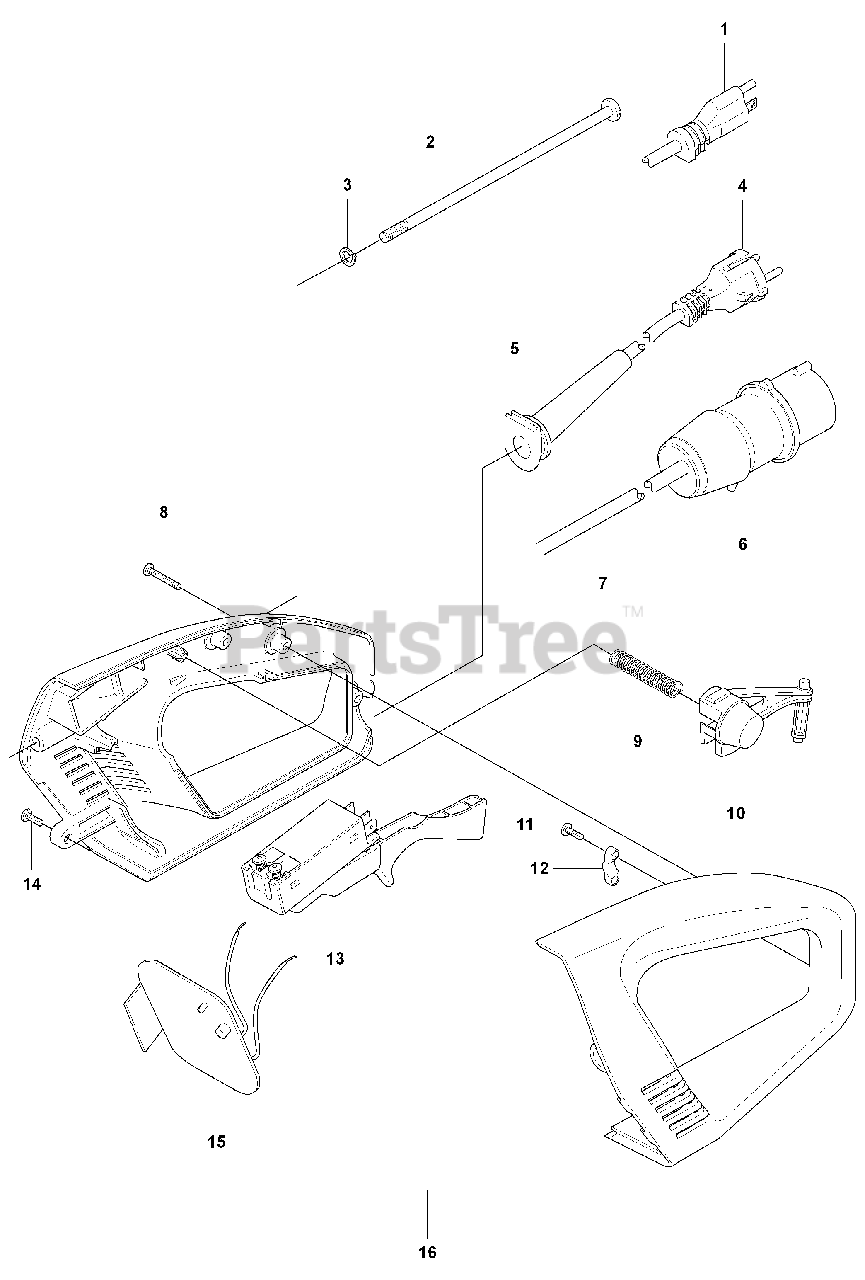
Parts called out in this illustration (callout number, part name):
1	CABLE
4	CABLE CPL 220V CL.1
5	CABLE SLEEVE
6	PLUG
7	CABLE 110V
9	SPRING
10	LOCKING BUTTON
15	ENGINE PROTECTION
16	HANDLE ASSY
